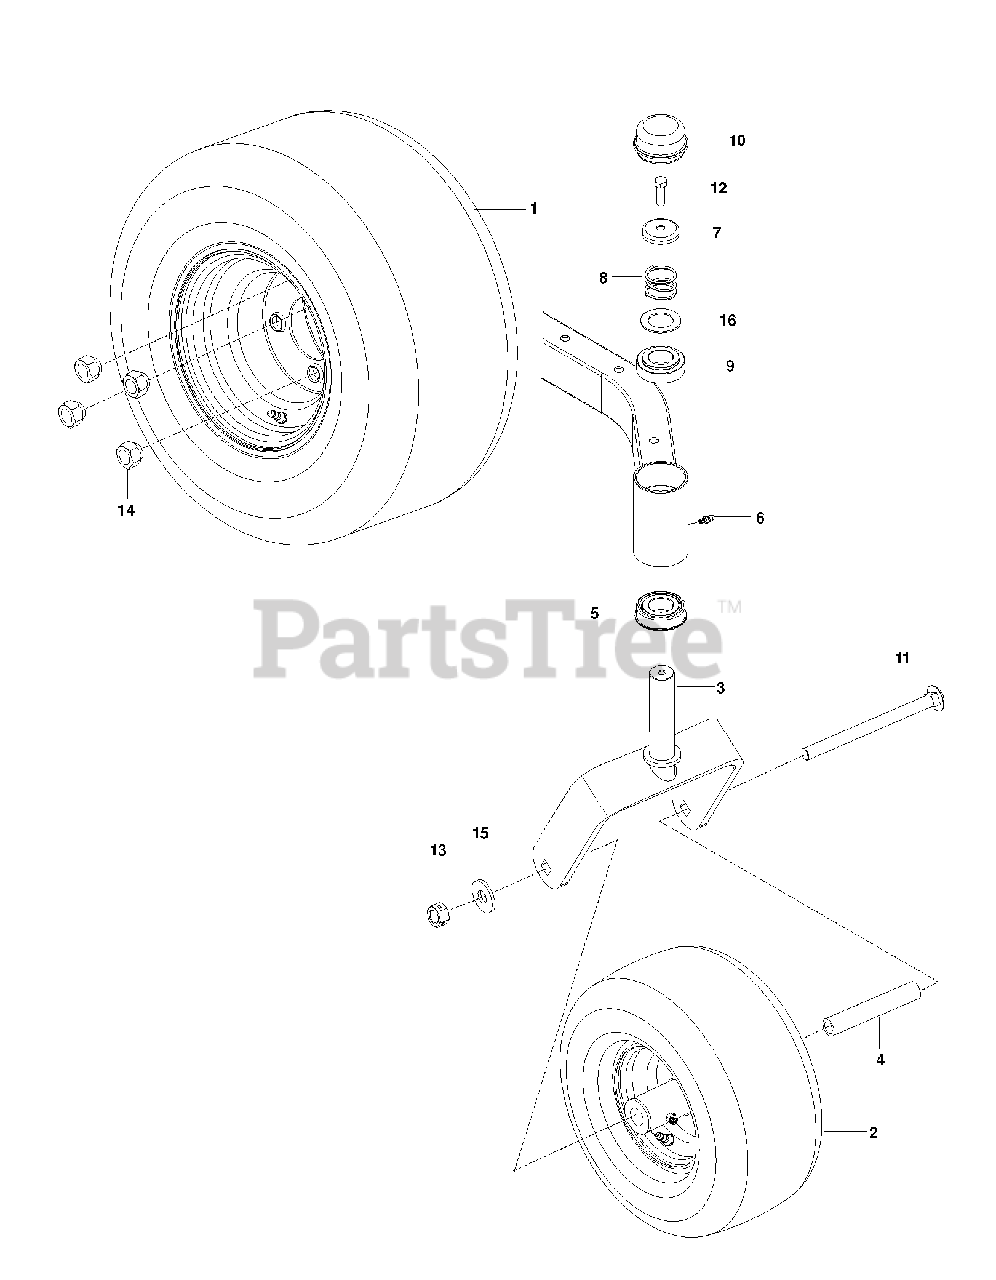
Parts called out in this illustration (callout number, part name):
1	WHEEL.A500.18 X 9.5-8.SILVER
2	WHEEL ASSY, WIDE, RZ
3	YOKE.CASTER.ORANGE
4	SPACER, PIVOT
5	BEARING FLANGED
6	ZERK, 3/16, DRIVE IN
7	CASTER.PLUG
8	SPRING, CASTER
9	BUSHING, CASTER
10	GREASE CAP
11	RHSNB 1/2-13 X 7.5
12	5/16-18X1 HHB G5W/NY
13	NUT 1/2-13 HEX CNTRLK GR 5 ZD
14	LUG NUT 1/2F
15	WASHER, 1.025 ID X 1.64
16	WASHER.9/16 X 1 3/8 X 12 GA.
